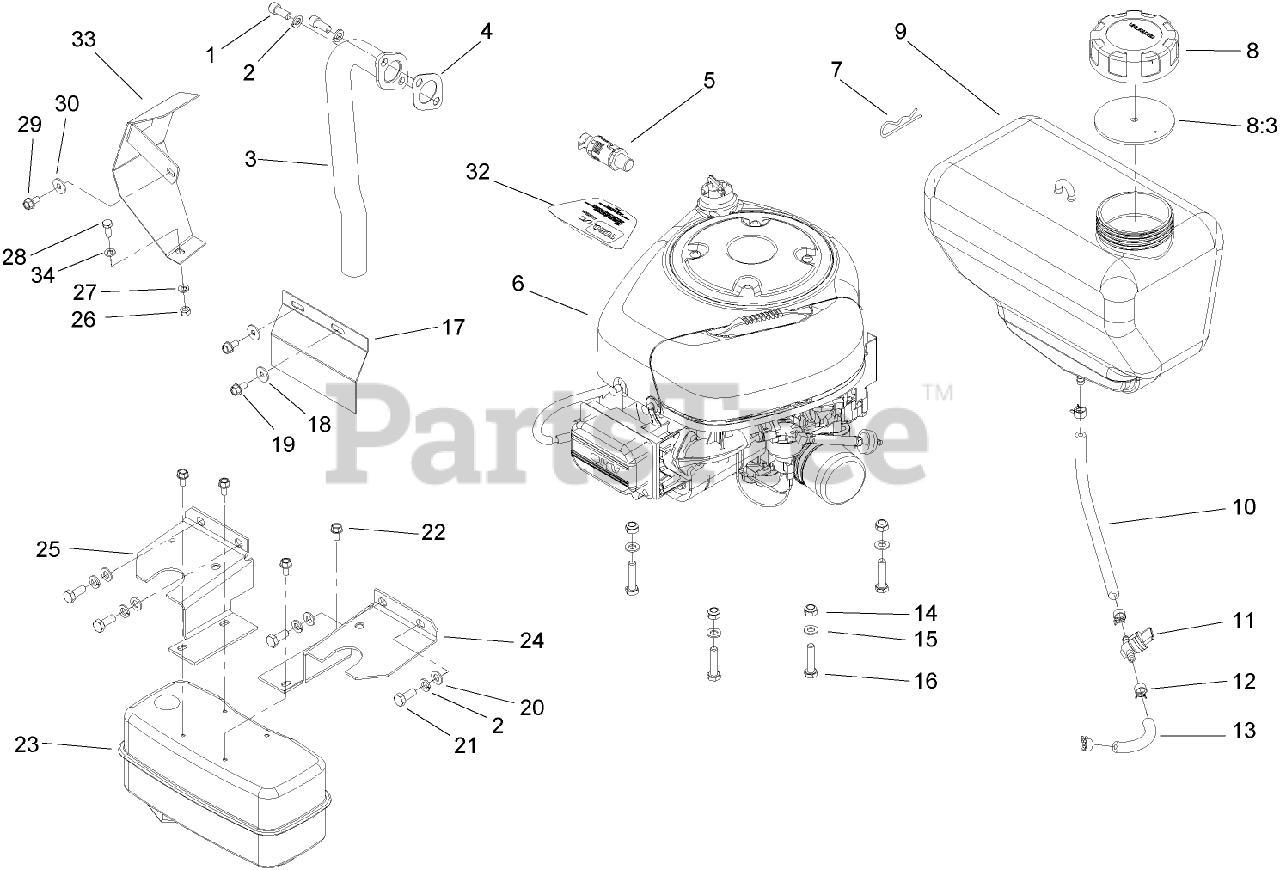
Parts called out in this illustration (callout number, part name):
1	SCREW-HH
3	TUBE-EXHAUST
4	GASKET-EXHAUST
5	VALVE-OIL DRAIN
6	Loose Parts Package
7	PIN-HAIR
8	GAS CAP ASM
8:3	GASKET-CAP, GAS
9	TANK-FUEL
10	LINE-FUEL
11	VALVE-TANK, FUEL
12	CLAMP-LINE, FUEL
13	LINE-FUEL
14	NUT-LOCK, NI
15	WASHER-PLAIN
16	SCREW-HH
17	COVER-FRONT
18	WASHER-FLAT
20	WASHER-PLAIN
21	SCREW-HH
23	MUFFLER
24	GUARD-MUFFLER, LH
25	GUARD-MUFFLER, RH
26	NUT-HEX
27	WASHER-SPRING
28	SCREW-HH
30	WASHER-FLAT
32	DECAL-ENGINE
33	Cover-Manifold, Exhaust
34	WASHER-FLAT
